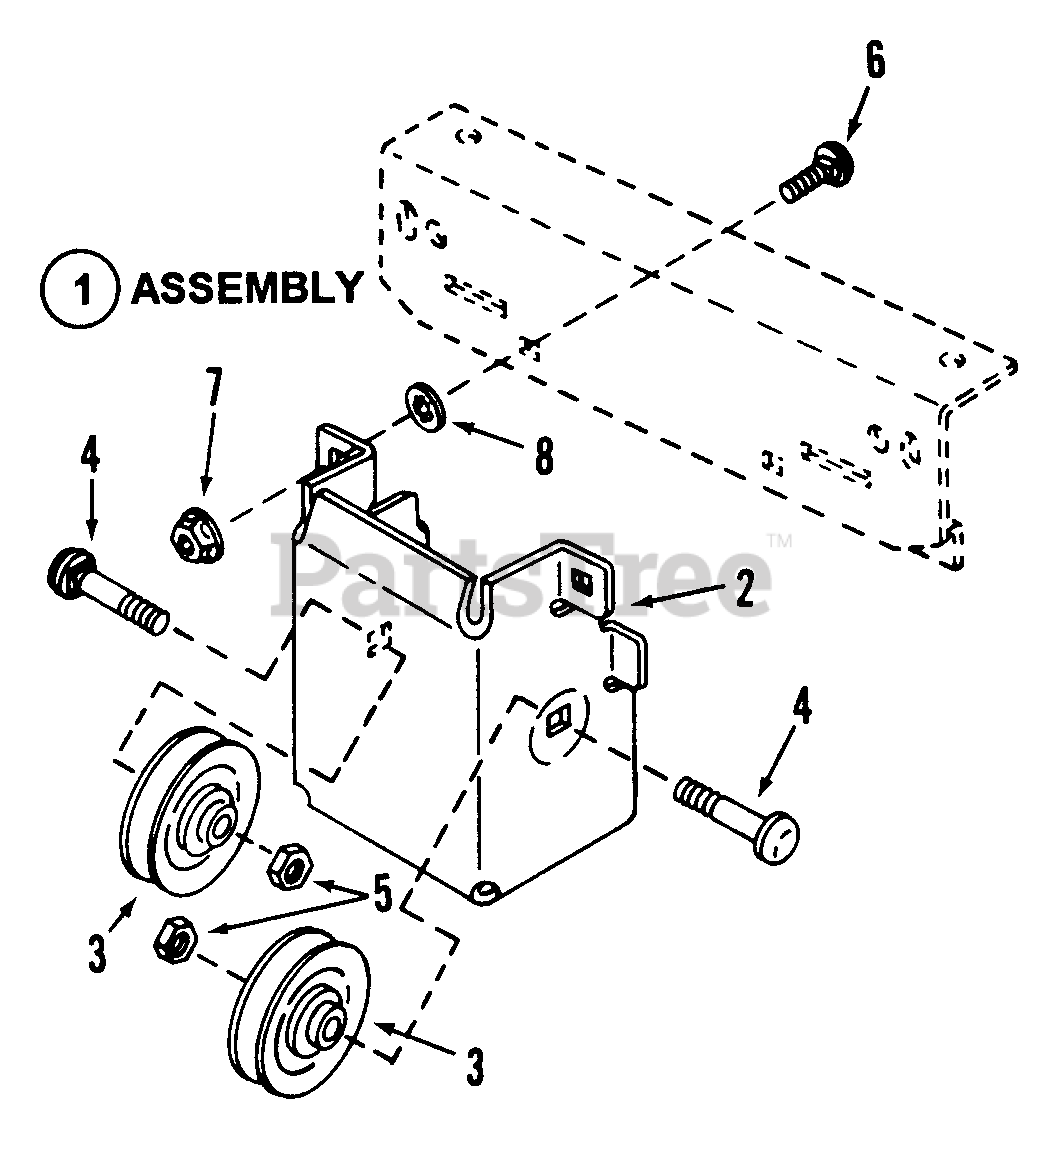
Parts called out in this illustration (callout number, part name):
1	ASSEMBLY, Mule Drive
2	BRACKET, Mule Drive
3	PULLEY, Belt Idler
4	BOLT, 3/8-16 x 1-1/2" Short Square Neck Carriage, Grade 5
5	NUT, 3/8-16 Hex Top Lock
6	* BOLT, 3/8-16 x 3/4" Square Neck Carriage, Grade 2
7	* NUT, 3/8-16 Hex Flange Lock
8	* RETAINER, 3/8 Bolt
